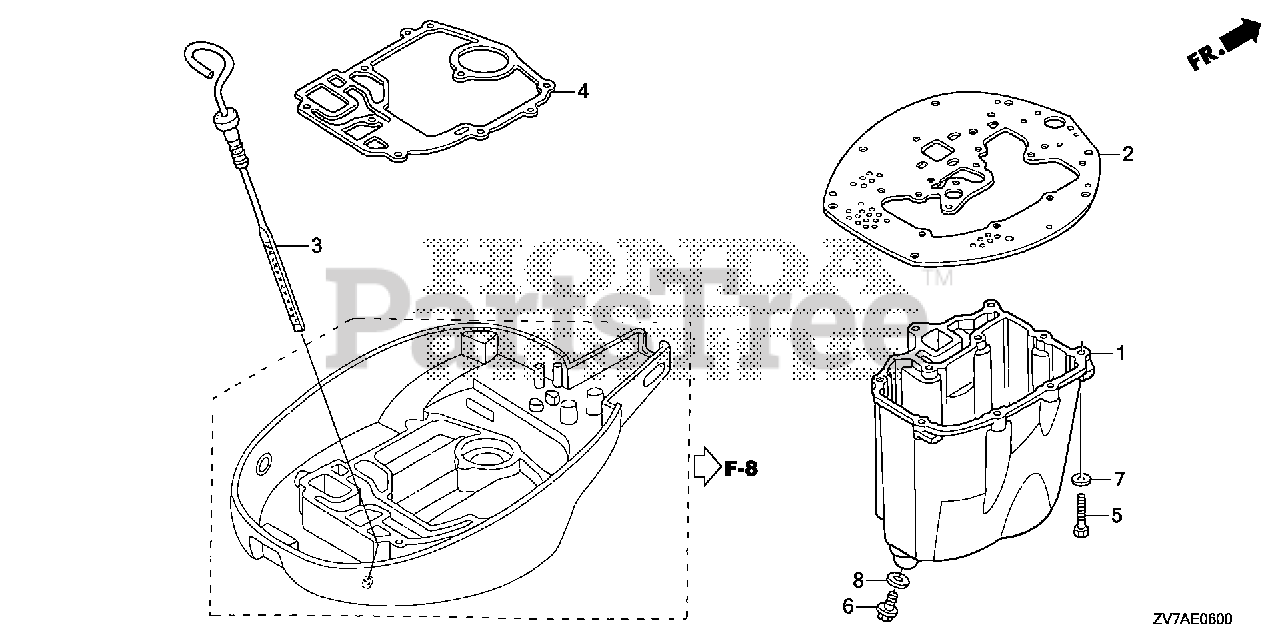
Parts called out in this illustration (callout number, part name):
1	PAN, OIL *TGRAY* (GRAY)
2	GASKET, OIL PAN
3	DIPSTICK, OIL
4	GASKET, ENGINE CASE (LOWER)
5	BOLT, HEX. (6X25)
6	BOLT, DRAIN PLUG
7	WASHER, PLAIN (6MM)
8	WASHER, DRAIN PLUG (12MM)
